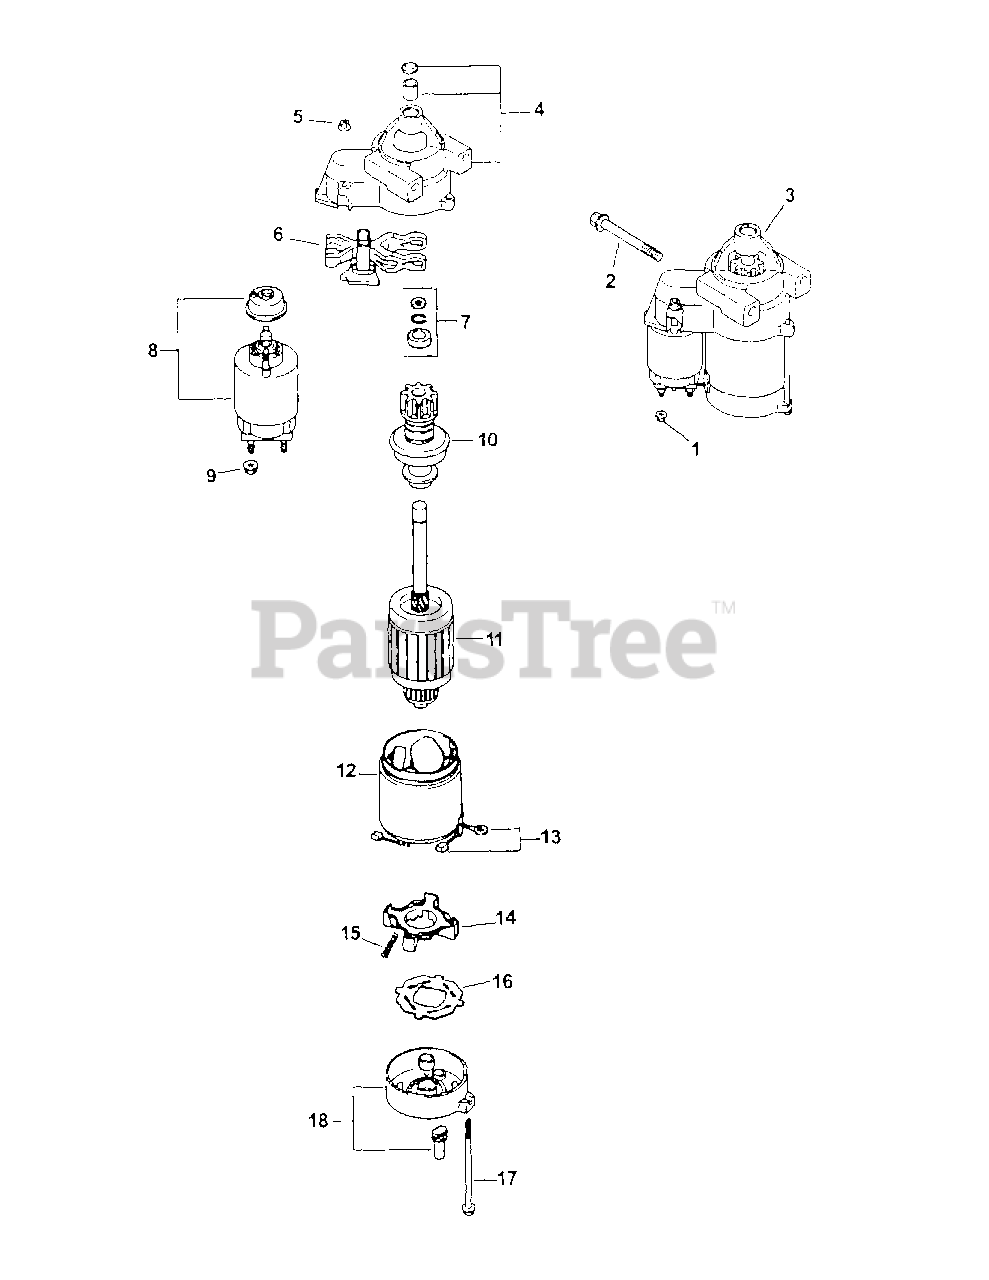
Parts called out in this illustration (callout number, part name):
1	Nut, Hex Flange
2	Screw, Hex Flange
3	Starter, Solenoid Shift
4	Drive, End Cap
5	Nut, Starter
6	Lever, Starter Drive
7	Kit, Starter Repair
8	Solenoid
9	Nut, Starter
10	Drive, Pinion
11	Armature, Starter
13	Kit, Brush
14	Holder, Brush
15	Spring, Brush
16	Insulator
18	Commutator, End
